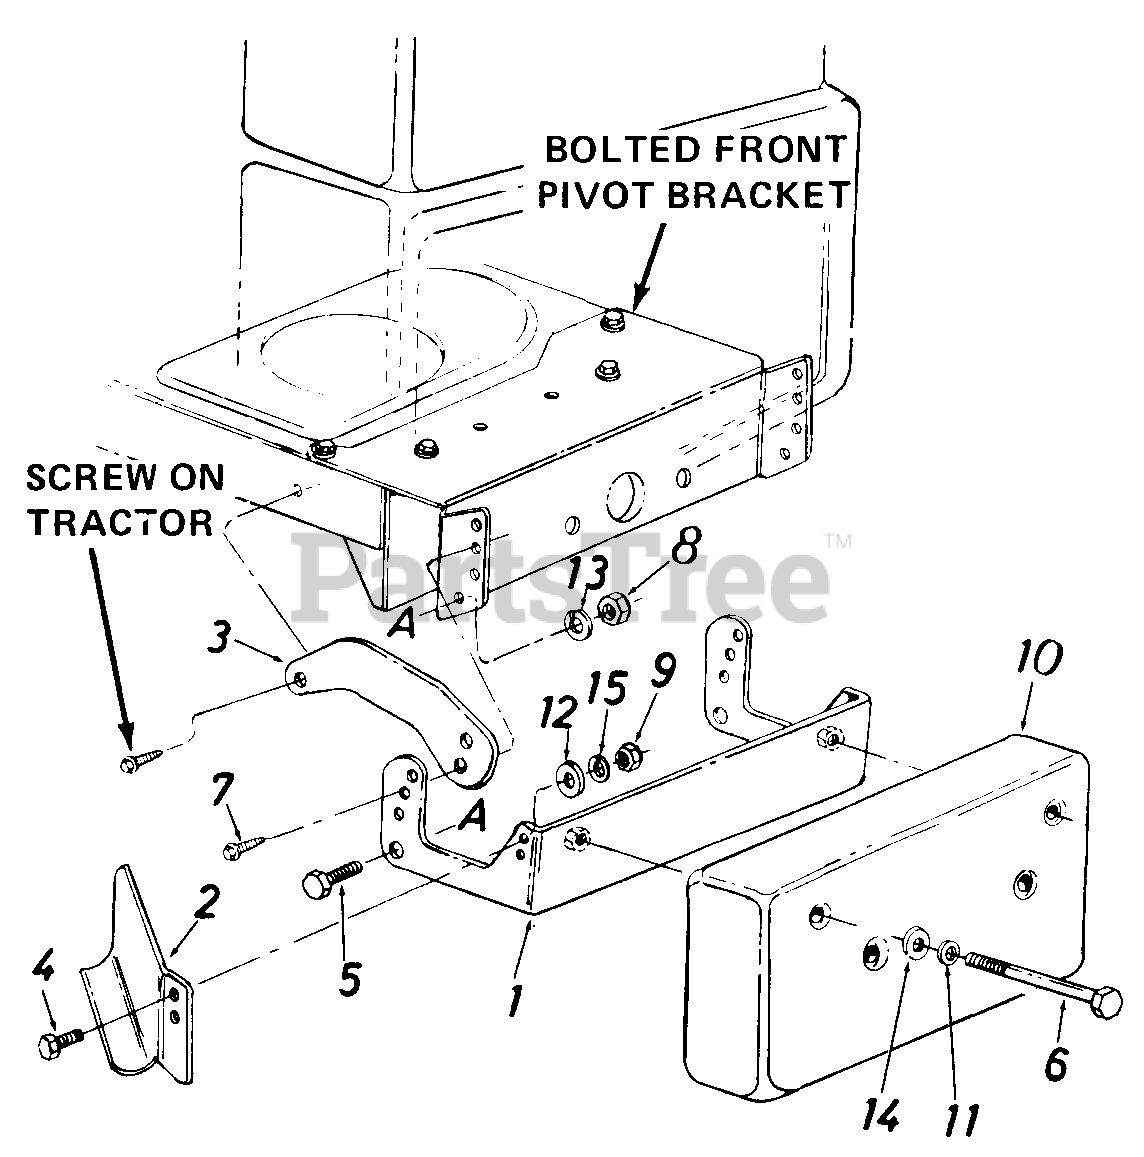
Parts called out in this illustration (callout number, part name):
1	Counterweight Bracket Ass'y.
2	Exhaust Deflector
3	Tie Strap
4	Hex Bolt 1/4-20 x .62" Lg.*
5	Hex Bolt7/16-20x 1.0" Lg.
6	Hex Bolt 3/8-16x4.5" Lg.
7	Hex AB Tap Scr. 5/16-18 x 1.0" Lg.
8	Hex Jam Nut 7/16-20 Thd.
9	Hex Nut 1/4-20 Thd.*
10	Front Counterweight-38 Lbs.
11	Bell-Wash..40" I.D. x .88" O.D.
12	Fl-Wash. .28" I.D. x.50" O.D.
13	L-Wash. 7/16" I.D.
14	Fl-Wash. .39" I.D. x 1.12" O.D.
15	L-Wash. 1/4" I.D.*
